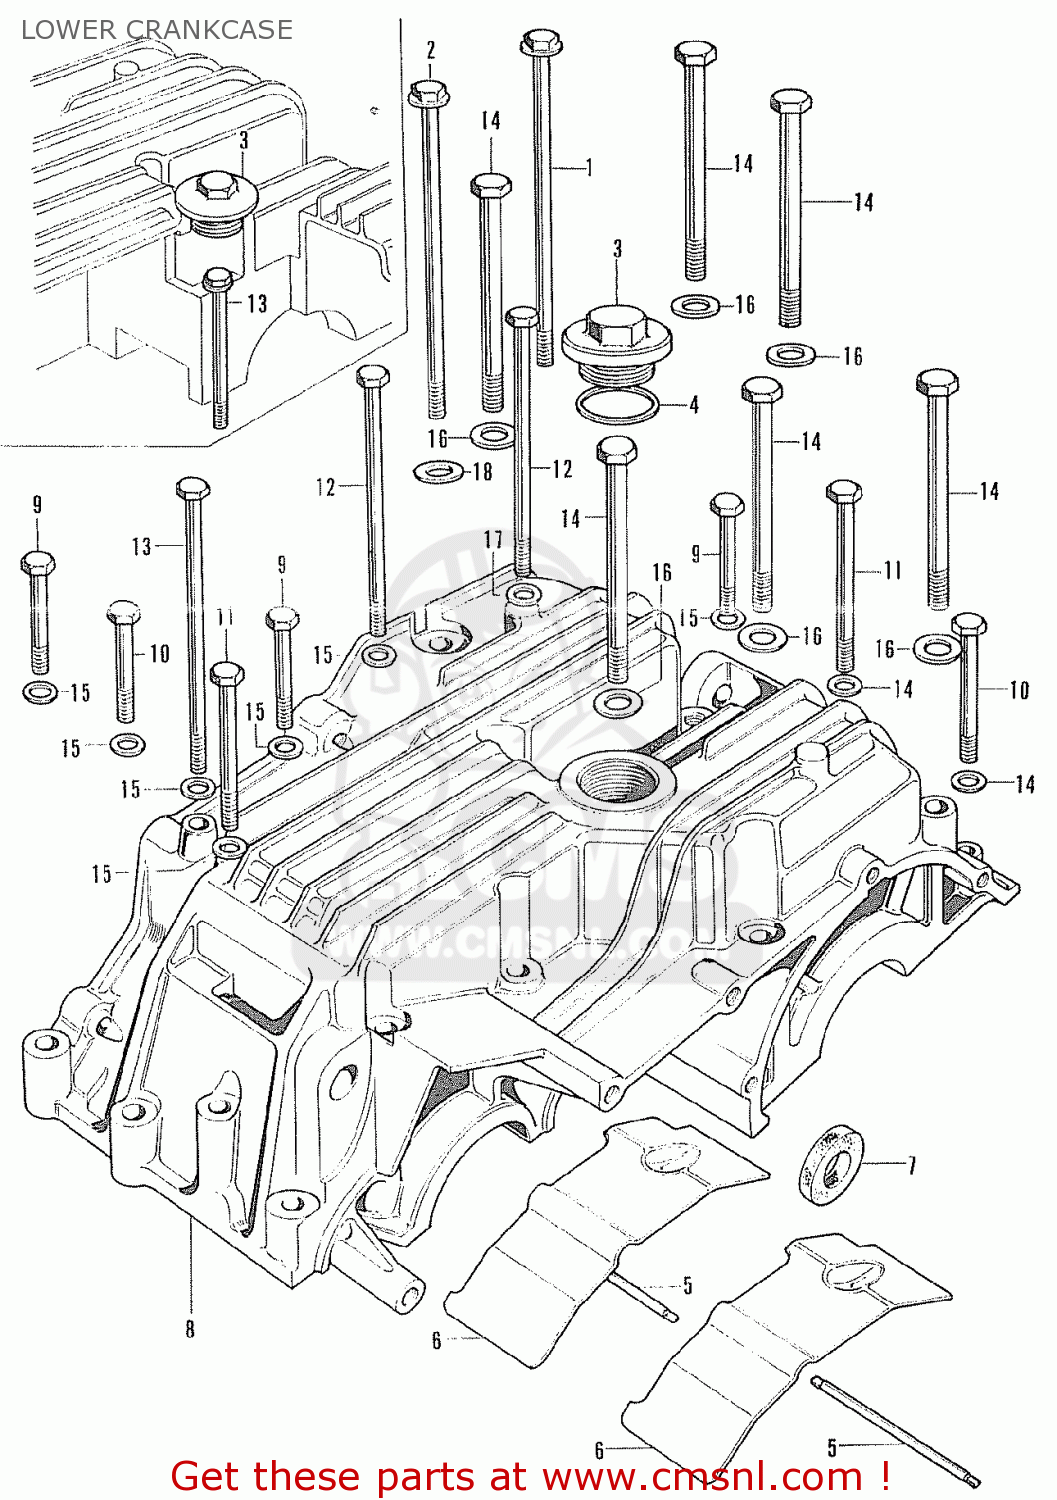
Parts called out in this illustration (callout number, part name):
1	BOLT,FLANGE 8X130
2	BOLT,HEX 8X135
3	BOLT DRAIN
4	BOLT,DRAIN.COCK
5	BAR,OIL SEPARATOR
6	SEPARATOR, OIL
7	OIL SEAL,12X25X45
8	CRANKCASE (LOWER)
9	BOLT,HEX 6X36
10	BOLT,HEX 8X40
11	BOLT,HEX 6X45
12	BOLT,HEX 6X56
13	BOLT, HEX., 6X95
14	BOLT HEX 6X112
15	BOLT HEX 8X95
16	WASHER,PLAIN, 6MM
17	WASHER,PLAIN,8MM
18	WASHER,SEALING
